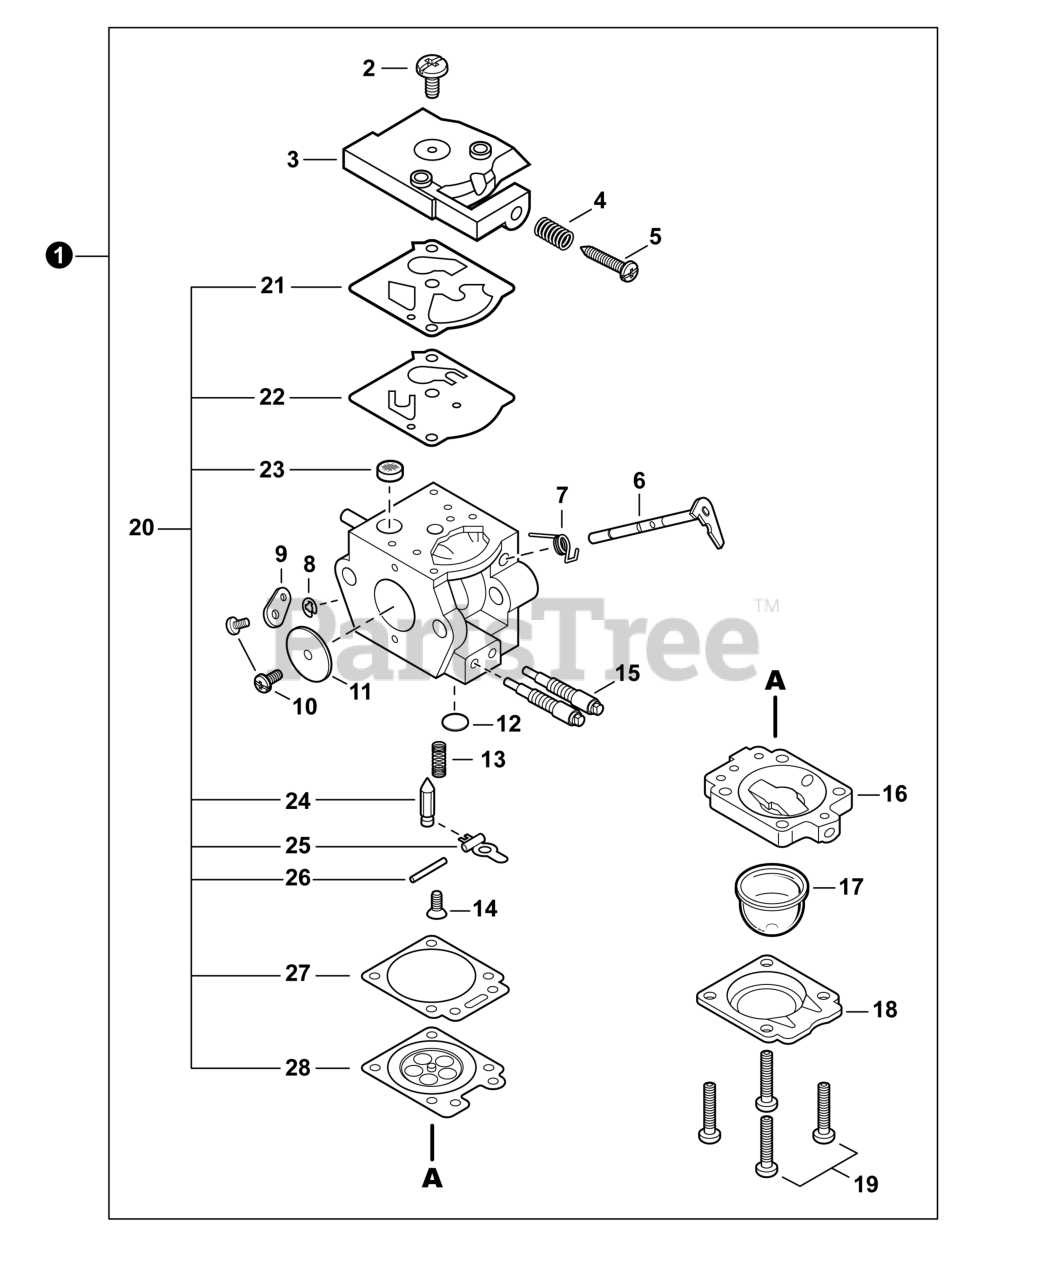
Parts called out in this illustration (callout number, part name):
1	CARBURETOR WTA-35
3	COVER, FUEL PUMP
4	SPRING, IDLE ADJUST
5	SCREW, IDLE ADJUST
6	SHAFT, THROTTLE
9	LEVER, THROTTLE
11	VALVE, THROTTLE
12	PLUG, WELCH
13	SPRING, METERING LEVER
15	NEEDLE, MIXTURE
16	BODY ASSY, PURGE
17	BULB, PURGE
18	RETAINER, PURGE BULB
20	REPAIR KIT, CARBURETOR
21	GASKET, FUEL PUMP
22	DIAPHRAGM, PUMP
23	SCREEN, FUEL INLET
24	VALVE, INLET NEEDLE
25	LEVER, METERING
26	PIN, METERING LEVER
27	GASKET, METERING DIAPHRAGM
28	DIAPHRAGM, METERING
